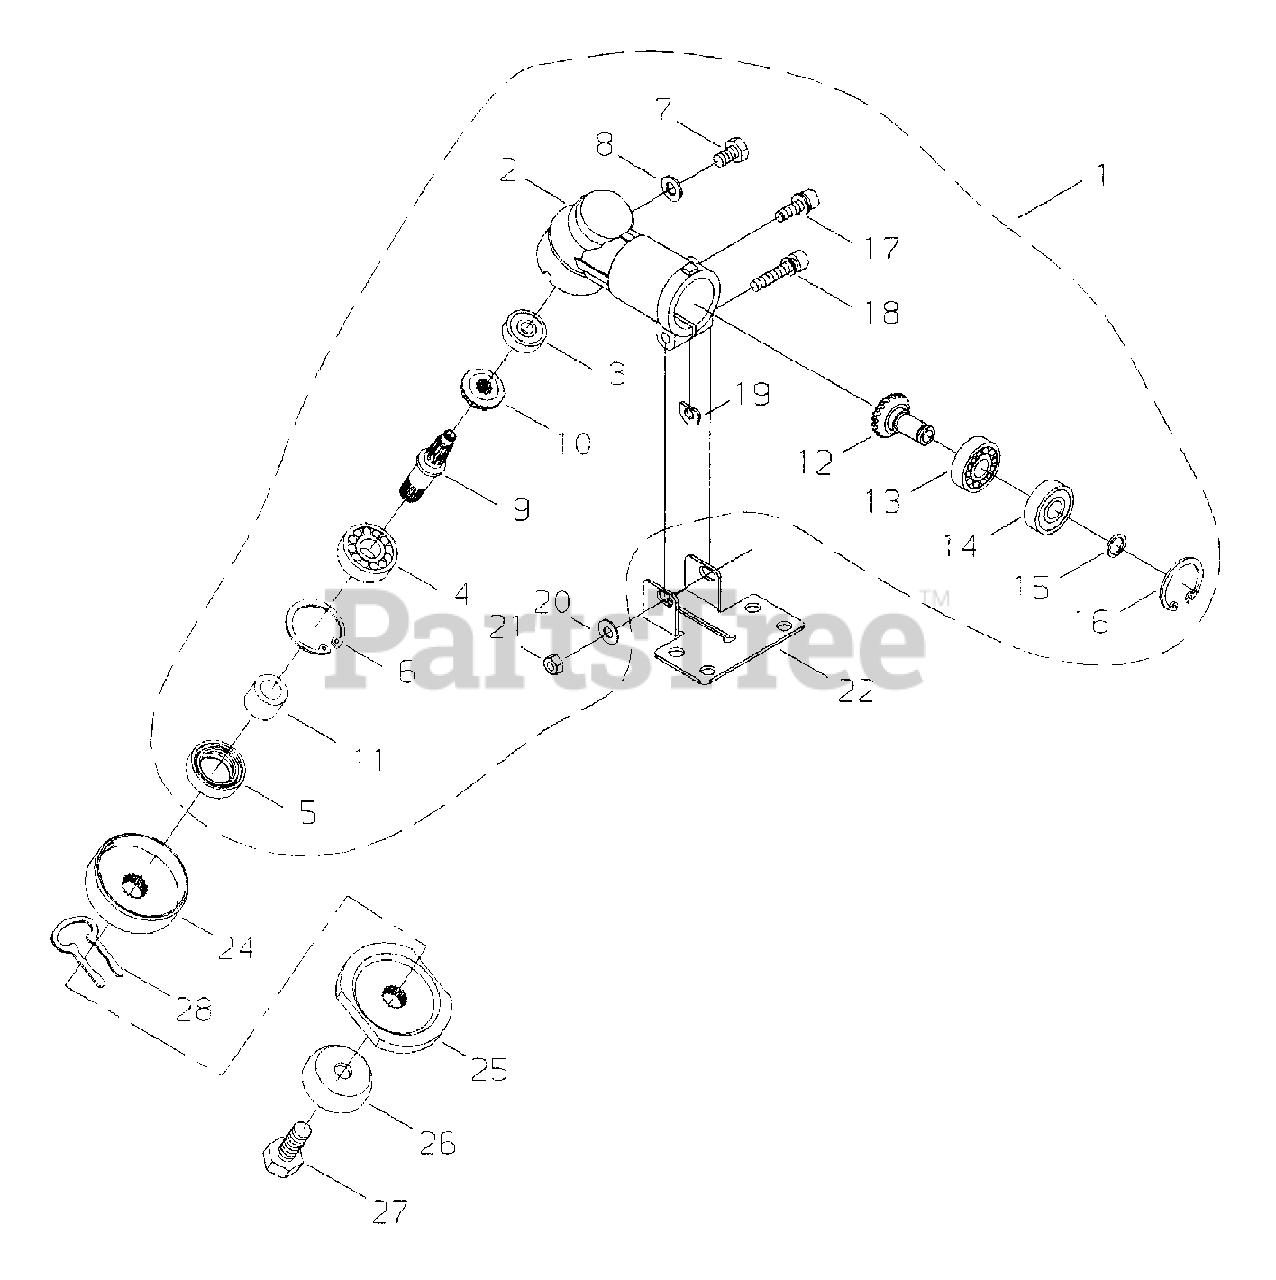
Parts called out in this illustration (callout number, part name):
1	GEAR CASE ASSY
2	CASE, GEAR
3	BEARING, BALL - 626
4	BEARING, BALL - 6000
5	SEAL, OIL
6	RING, RETAINING - 26
7	BOLT - 6X10
8	WASHER
9	GEAR - SHAFT
10	GEAR - BEVEL
11	COLLAR
12	GEAR - SHAFT
13	BEARING, BALL - 608
14	BEARING, BALL - 608ZZ
15	RING, RETAINING
16	RING, RETAINING - 22
17	SCREW - 5X16
18	SCREW - 5X35
19	SHIM
20	WASHER - 5
22	CLAMP - LOWER
24	HOLDER - A
25	HOLDER B, REPLACES 22035-13251, REPLACES 22553-13250
26	GUARD
27	BOLT - 7X18 -- LEFT HAND
28	SLIDE CLIP
